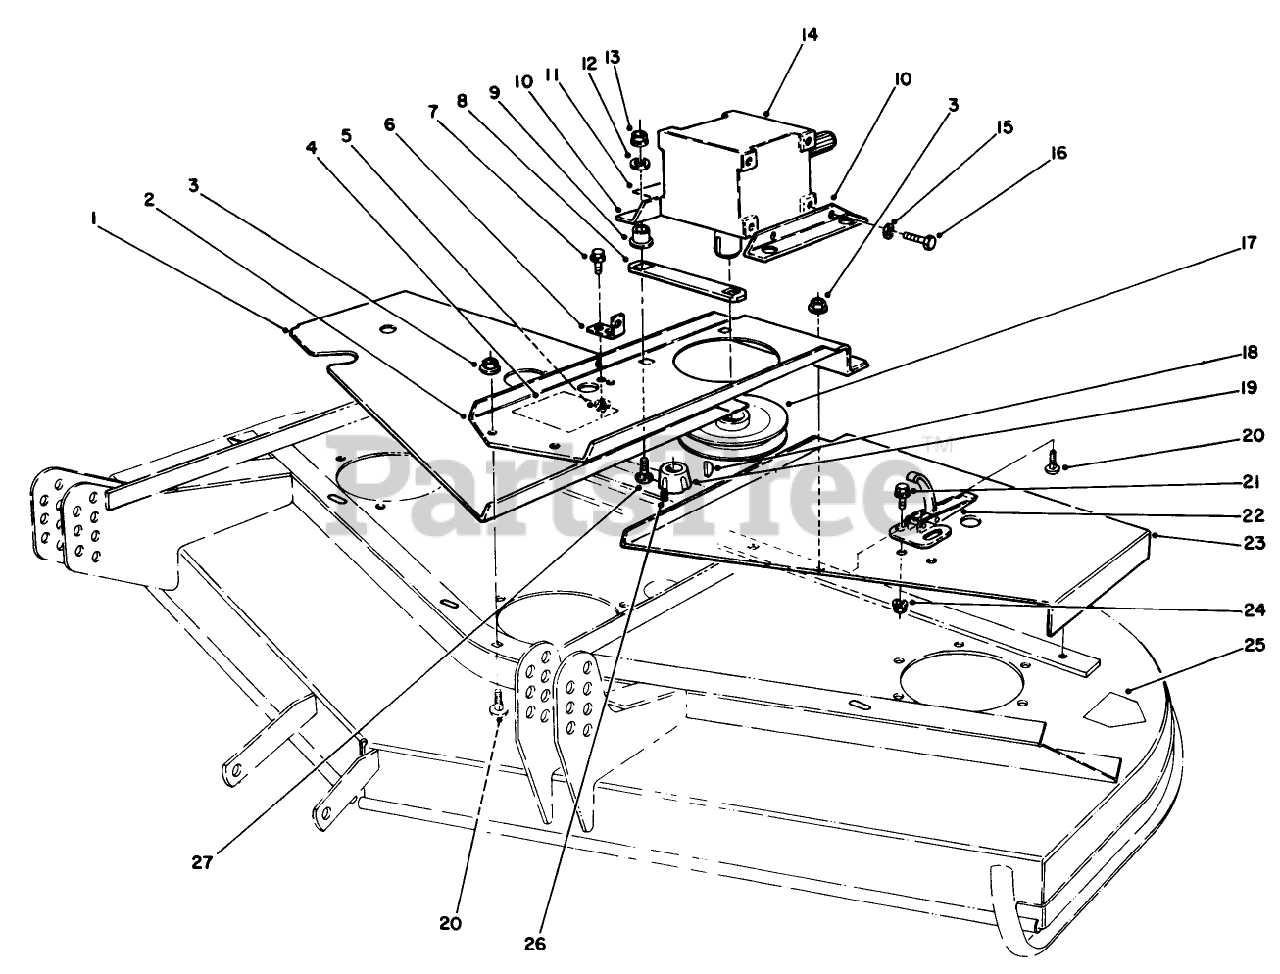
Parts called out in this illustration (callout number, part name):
1	Cover RH
2	Base-Gear Box
3	NUT-HHF, WHIZ
4	DECAL
5	NUT-HF
6	Bracket-Extension
7	SCREW-HH
8	Cover-Gear Box
9	MOUNT
10	Bracket-Gearbox
11	DECAL-OIL
12	WASHER
13	NUT-LOCK, SIDE
14	Gearbox
15	WASHER-LOCK
16	SCREW-HH
17	PULLEY
18	KEY-WOODRUFF
19	Bushing-Taper Lock (Incl. Ref. #26)
20	SCREW-CARR
21	SCREW-HWH
22	CLAMP-SLOTTED
23	Cover LH
24	NUT-LOCK, FLANGE
25	DECAL-DANGER
26	SCREW-SET, HSH
27	SCREW-CARR
